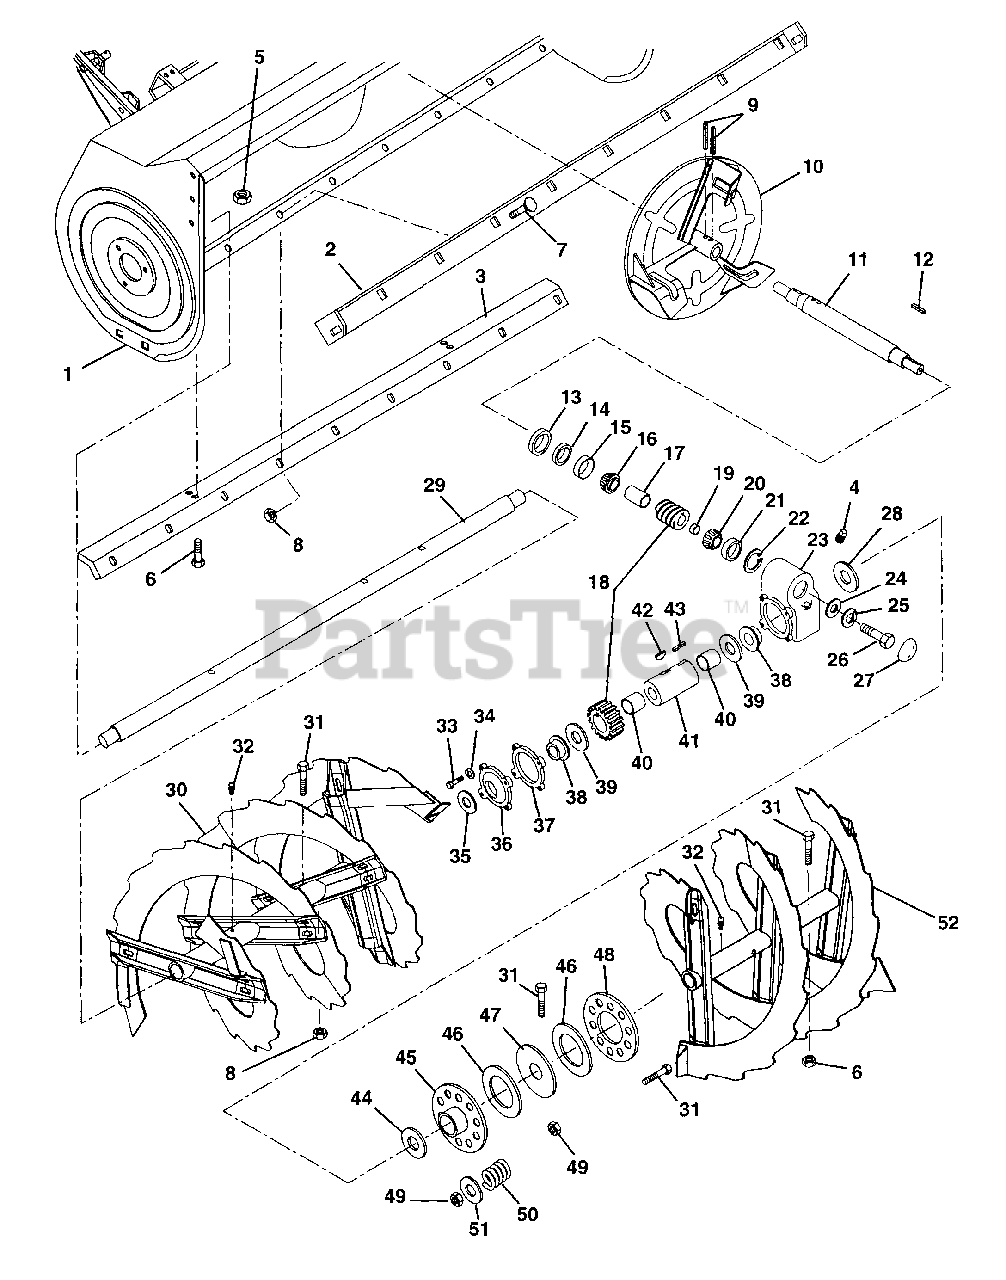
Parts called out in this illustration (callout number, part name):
1	48 AUGER/16 IMPELLER HOUSING
2	SCRAPER BLADE
3	SCRAPER BLADE BRACE
4	PIPE PLUG
5	@NUT-LK-CTR .38-16 YWZC
6	@BLT-HEX .38-16X.75 GR5 YWZC
7	BLT-RDHDSQSHK.31-18X.75 GR2 YW
8	@NUT-LK-CTR .31-18 YWZC
9	PIN-ROLL .313X1.75
10	FAN - 16"
11	WORM SHAFT
12	KEY-SQ .188X1.0X.188 SAE 8630
13	ADJUSTMENT PLUG
14	SEAL 1.125X1.375X.125
15	BRG-CUP1.980X.420
16	BRG-CONE 1.0X.58
17	BEARING SPACER 1.032X1.25X1.78
18	WORM & GEAR SERVICE ASSEMBLY
19	BSHG, SPCR .755X1.12X.50 PM
20	BRG-CONE .750X.61
21	BRG-CUP 1.781X.475
22	RG-RTNG-INT 1.781X.062
23	GEAR CASE - CAST IRON
24	WSHR-FL-STL .328X1.0X.094 YWZC
25	@WSHR-LK .31X.078 REG YWZC
26	@BLT-HEX .31-18X.75 GR5 YWZC
27	DUST CAP
28	SEAL 1.625X2.125X.250
29	48 INCH RAKE SHAFT
30	RAKE, RIGHT-48(1.12ID X 15.75)
31	@BLT-HEX .31-18X2.00 GR5 YWZC
32	FTG-LUBE .25-28X.256 YWZC
33	@BLT-HEX .25-20X.75 GR5 YWZC
34	@WSHR-LK-EXT.262X.502X.026YWZC
35	SEAL 1.625X2.125X.250
36	GEAR CASE COVER
38	BSHG-FLG .683X1.87X1.68X2.250
39	WSHR-FL-STL 1.625X2.500X.012
40	BSHG-SLV 1.125X1.250X1.000
41	GEAR CASE SHAFT
42	KEY-FTHR .25X.875X.25 SAE 8630
43	KEY-SQ .25X.625X.375
44	WSHR-FL-NYL 1.625X2.500X.060
46	FRICTION DISC
47	DRIVEN PLATE
48	PRESSURE PLATE
49	@NUT-LK-CTR .31-18 YWZC
50	SG-COMP .156X.665X.75
51	@WSHR-FL-STL.344X.688X.065YWZC
52	RAKE, LEFT-48"(1.12ID X 15.75)
